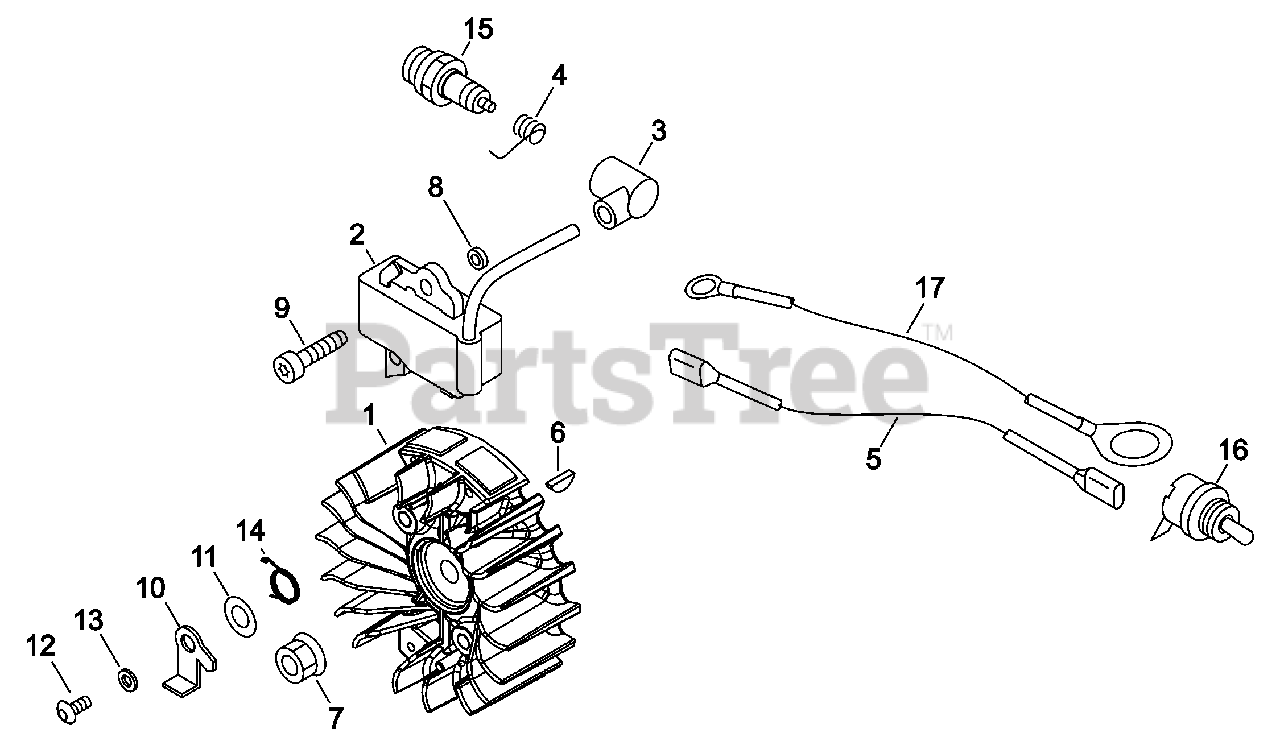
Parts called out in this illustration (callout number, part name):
1	FLYWHEEL
2	COIL, IGNITION
3	CAP, SPARK PLUG
4	TERMINAL, SPARK PLUG
5	LEAD - IGNITION
6	KEY, WOODRUFF
7	NUT, FLANGE M8
8	WASHER 5.2×12×3
9	BOLT, TORX 5×20
11	WASHER 5.5×12×0.8
12	BOLT 5×14
13	SPACER 5.2×8×2.1
14	SPRING, TORSION
15	SPARK PLUG - BPM8Y
16	SWITCH, ON-OFF
17	LEAD - GROUND L= 255
